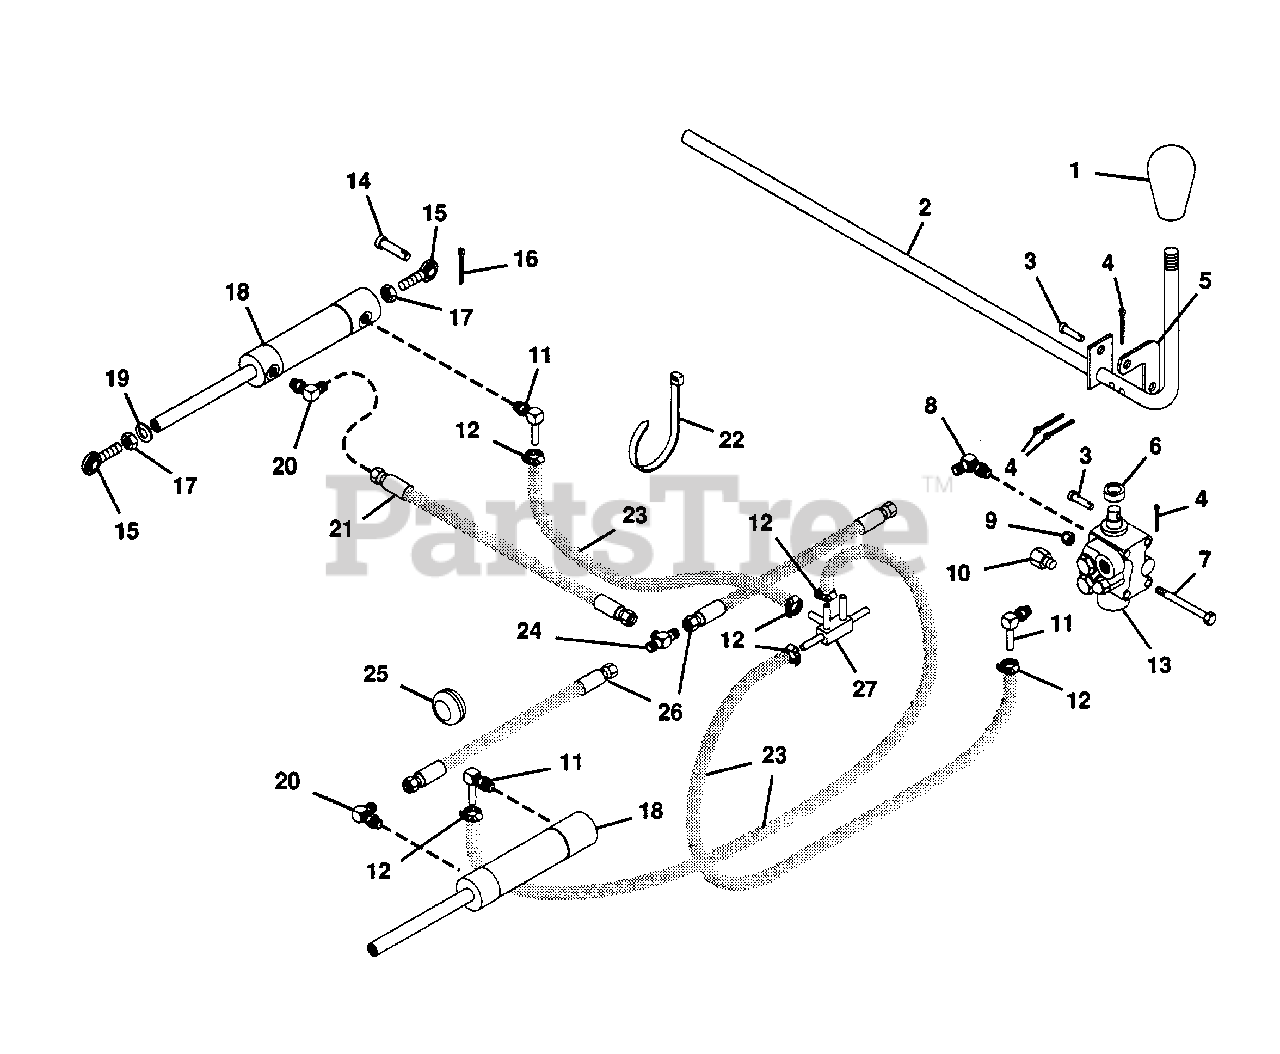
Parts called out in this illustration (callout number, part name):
1	Knob, PTO
2	Weldment, Lift Lever
3	Pin, Clevis
4	Pin, Cotter .094x.75
5	Rod, Hydraulic Control
6	Bush., St. .700x1.00x.300 Stl.
7	Bolt, Hex 1/4-20x2.75
8	Adapter
9	Nut, Lock 1/4-20
10	Plug, PH 05PO-4
11	Adapter, 4601-6-6
12	Clamp, Hose
13	Valve, Hydraulic
14	Pin, Clevis .50x1.330
15	Assembly, Rod End R.H.
16	Pin, Cotter .125x1.25
17	Nut, Jam 1/2-20
18	Cylinder, Lift
19	Washer, Lock 1/2 Reg.
20	Adapter, PH 2503-6-6
21	Assembly, Hydraulic Hose
22	Tie Wrap, Black
23	Hose, Hydraulic
24	Adapter, Tee
25	Grommet
26	Assembly, Hydraulic Hose
27	Manifold
